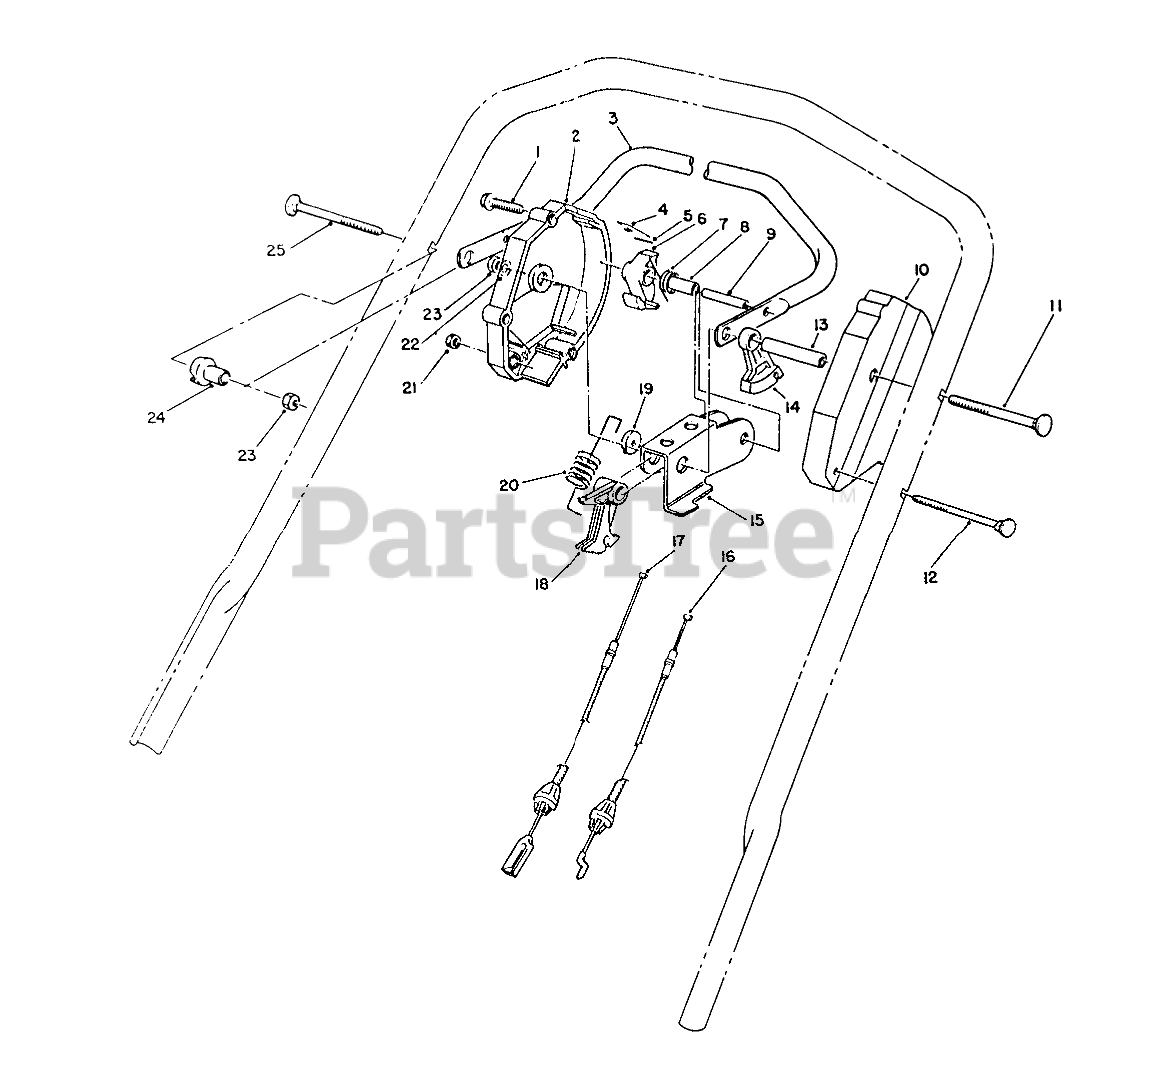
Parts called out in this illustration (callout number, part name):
1	SCREW-HWHTF
2	Housing-Control
3	Bar-Control
4	SPRING-LEAF
5	PIN-INSERT
6	HOOK-CONTROL
7	SPRING-TORSION
8	SPACER
9	PIN-ROLL, SLOTTED
10	HOUSING-CONTROL, LH
11	Screw-Handle
12	HANDLE SCREW
13	TUBING-SPACER
14	LEVER-TRACTION
15	ROCKER
16	TRACTION CABLE
17	BBC CABLE ASSEMBLY
18	LEVER-CABLE
19	WASHER-NYLON
20	SPRING-DETENT
21	NUT-HEX
22	WASHER-PLAIN
23	NUT-LOCK, NI
24	SPACER-SUPPORT
25	SCREW-HANDLE
